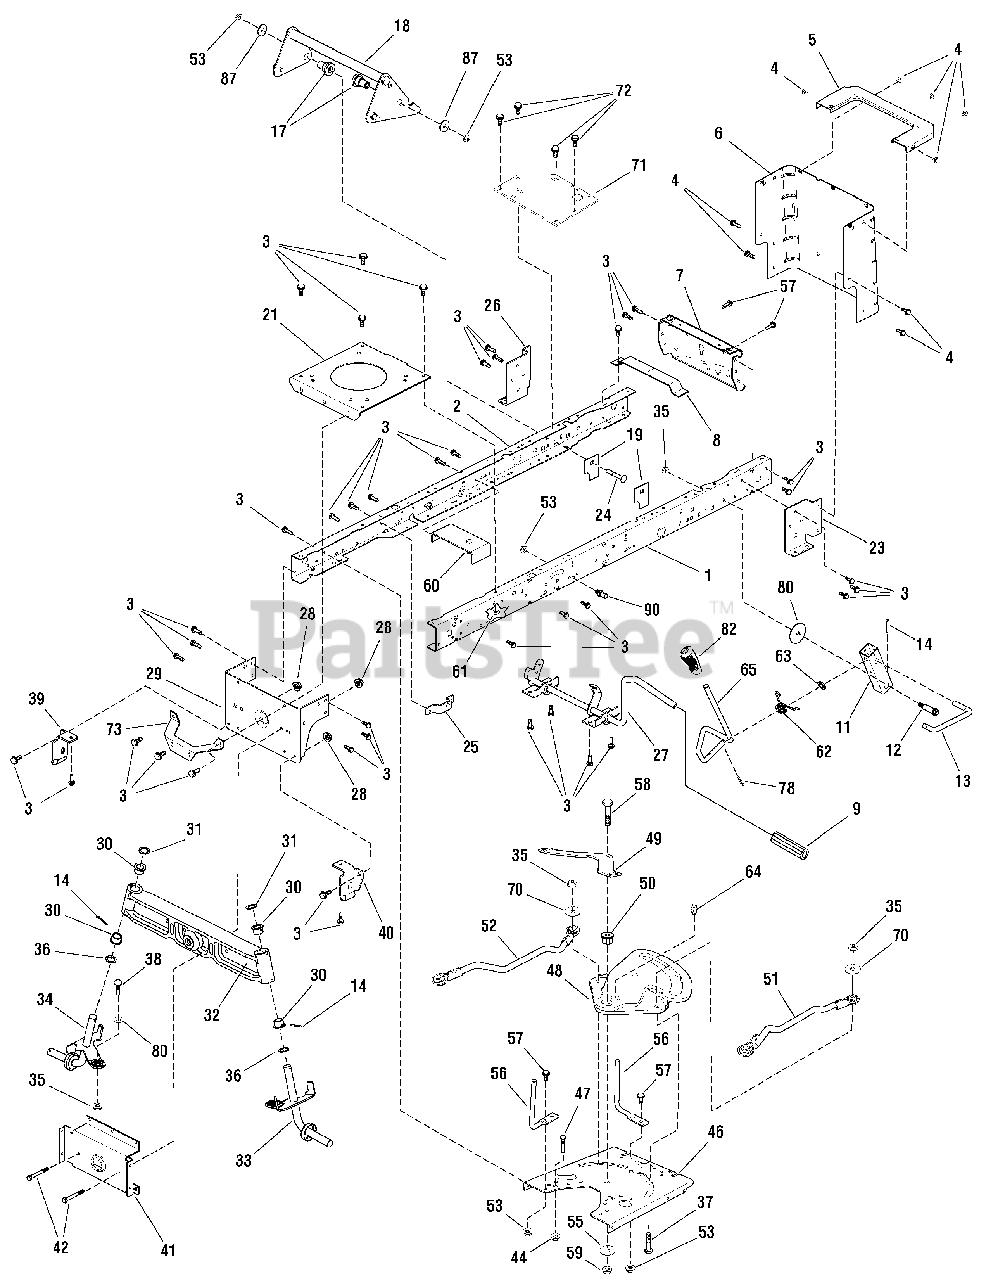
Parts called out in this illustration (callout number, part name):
1	RAIL, Frame, Right
2	RAIL, Frame, Left
3	CAPSCREW, 5/16-18 x 3/4
4	SCREW, Self tap, SEMS, #10C x 1/2
5	TOP, Rear Plate
6	PLATE, Rear
7	PLATE, Hitch
8	BRACKET, Battery Support
9	PEDAL, Clutch and Brake
11	BRACKET, Pivot
12	BOLT, Shoulder, 3/8-16 x 1/2
13	LINK, Lift Handle
14	COTTER PIN, 1/8 x 1-1/4
17	SPACER, Lifter
18	LIFTER ASSEMBLY
19	PLATE, Stiffening
21	PLATE, Engine
23	BRACKET, Transaxle Mount, Left
24	BOLT, Carriage, 3/8-16 x 2 1/2
25	BRACKET, Bellcrank
26	BRACKET, Transaxle Mount, Right
28	NUT, Hex Flange, 5/16F
29	BRACKET, Rear Hanger
30	BEARING, Spindle, LT
31	WASHER, Flat, 1
32	AXLE, Cast Iron
33	SPINDLE ASSEMBLY, Left
34	SPINDLE ASSEMBLY, Right
35	NUT, Hex Flange, Centerlock, 3/8-16
36	WASHER, Flat, 3/8
37	BOLT, Shoulder, 3/8-16 X 1
39	HANGER, Deck, Right
40	HANGER, Deck, Left
41	AXLE, Hanger
42	BOLT, Hex, 5/16-24 x 2-3/4
44	NUT, Hex Flange, 5/16-18
46	PLATE, Steering Mount
47	SCREW, Guide
48	STEERING CAM
49	SECTOR, Gear Support
50	BEARING, Sector Gear
51	LINK, Drag, Left
52	LINK, Drag, Right
53	NUT, Hex Flange, 3/8-16
55	WASHER, FLAT, 1-1/4
56	ROD, Belt Guide
57	SCREW, 3/8-16
58	CAPSCREW, Hex Head, 5/16-18 x 1-3/4
59	NUT, Flange Lock, 5/16-18
60	IDLER BRACKET ASSEMBLY, Secondary
61	NUT, Hex Flange, 5/16-18
62	SPRING, Torsion
63	WASHER, FLAT, 1
64	FITTING, Lube 1/4-28 Taper, Thread Forming
65	HANDLE, Lift
70	WASHER, Flat 1-1/4
71	BRACKET, Idler Pivot
72	SCREW, 5/16-18 X .50
73	BRACKET, Muffler Mounting
78	HAIR PIN
80	WASHER, Flat, 2-1/4
87	WASHER, Flat, 3/4
90	PIN,Threaded Shoulder 3/8-16 x 1-1/2
